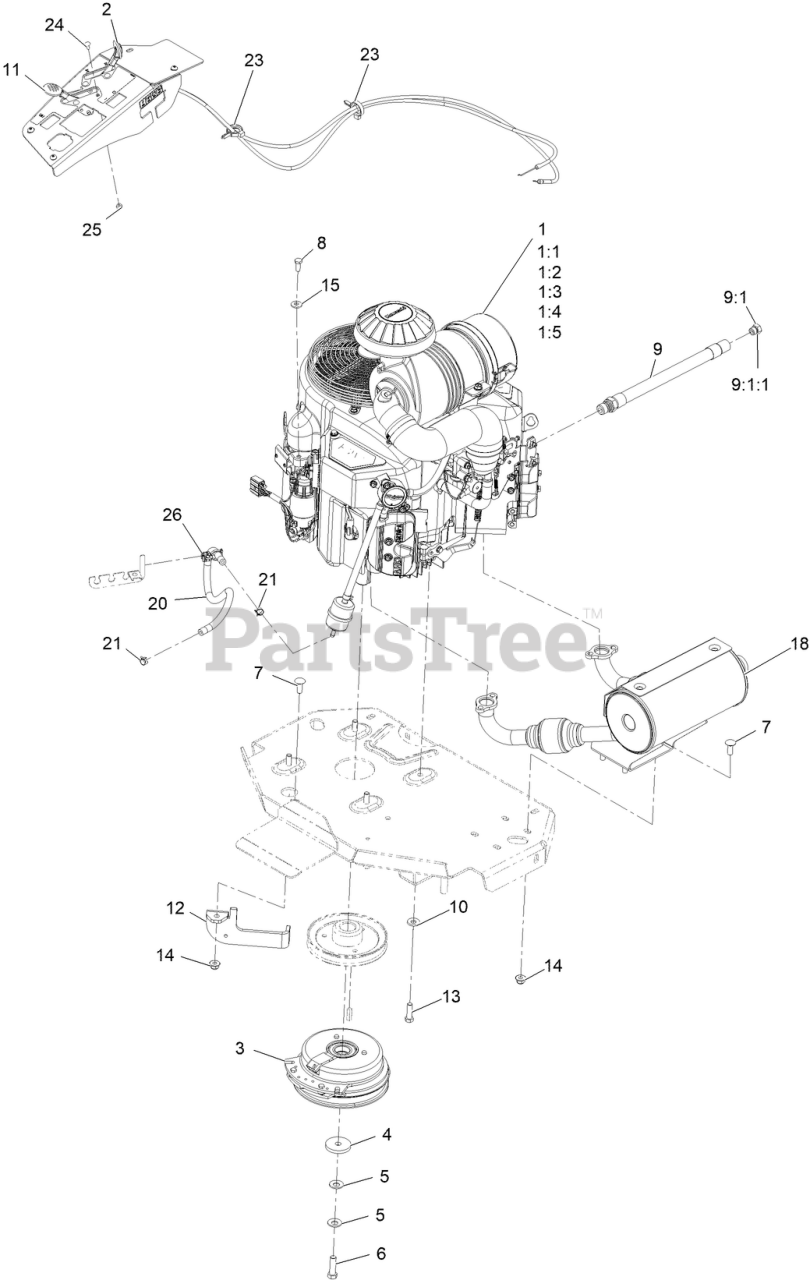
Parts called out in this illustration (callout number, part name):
1	Engine-Kawasaki
1:1	FILTER-OIL KAW
1:2	ELEMENT-FILTER, AIR (OUTE
1:3	ELEMENT-FILTER, AIR (INNE
1:4	FILTER-FUEL
1:5	SPARK PLUG
2	ASM, CHOKE CABLE
3	CLUTCH KIT
4	WASHER-CLUTCH
5	WASHER-SPRING
6	SCREW-HH 7/16-20 X 1 1/2 W/LOCTITE
7	SCREW-CARR
8	SCREW-HH
9	ENGINE OIL DRAIN HOSE ASM
9:1	PLUG-HH
9:1:1	O-RING
10	WASHER-BELLEVILLE
11	ASM,THROTTLE CABLE
12	Bracket-Clutch Anchor
13	SCREW-HH
14	NUT-HF, NI
15	WASHER-SPRING
18	KIT, MUFFLER
20	HOSE-FUEL
21	CLAMP-HOSE
23	CLAMP-HOSE
24	BOLT-CARR
25	NUT-LOCK, NI
26	Clip-Edge
